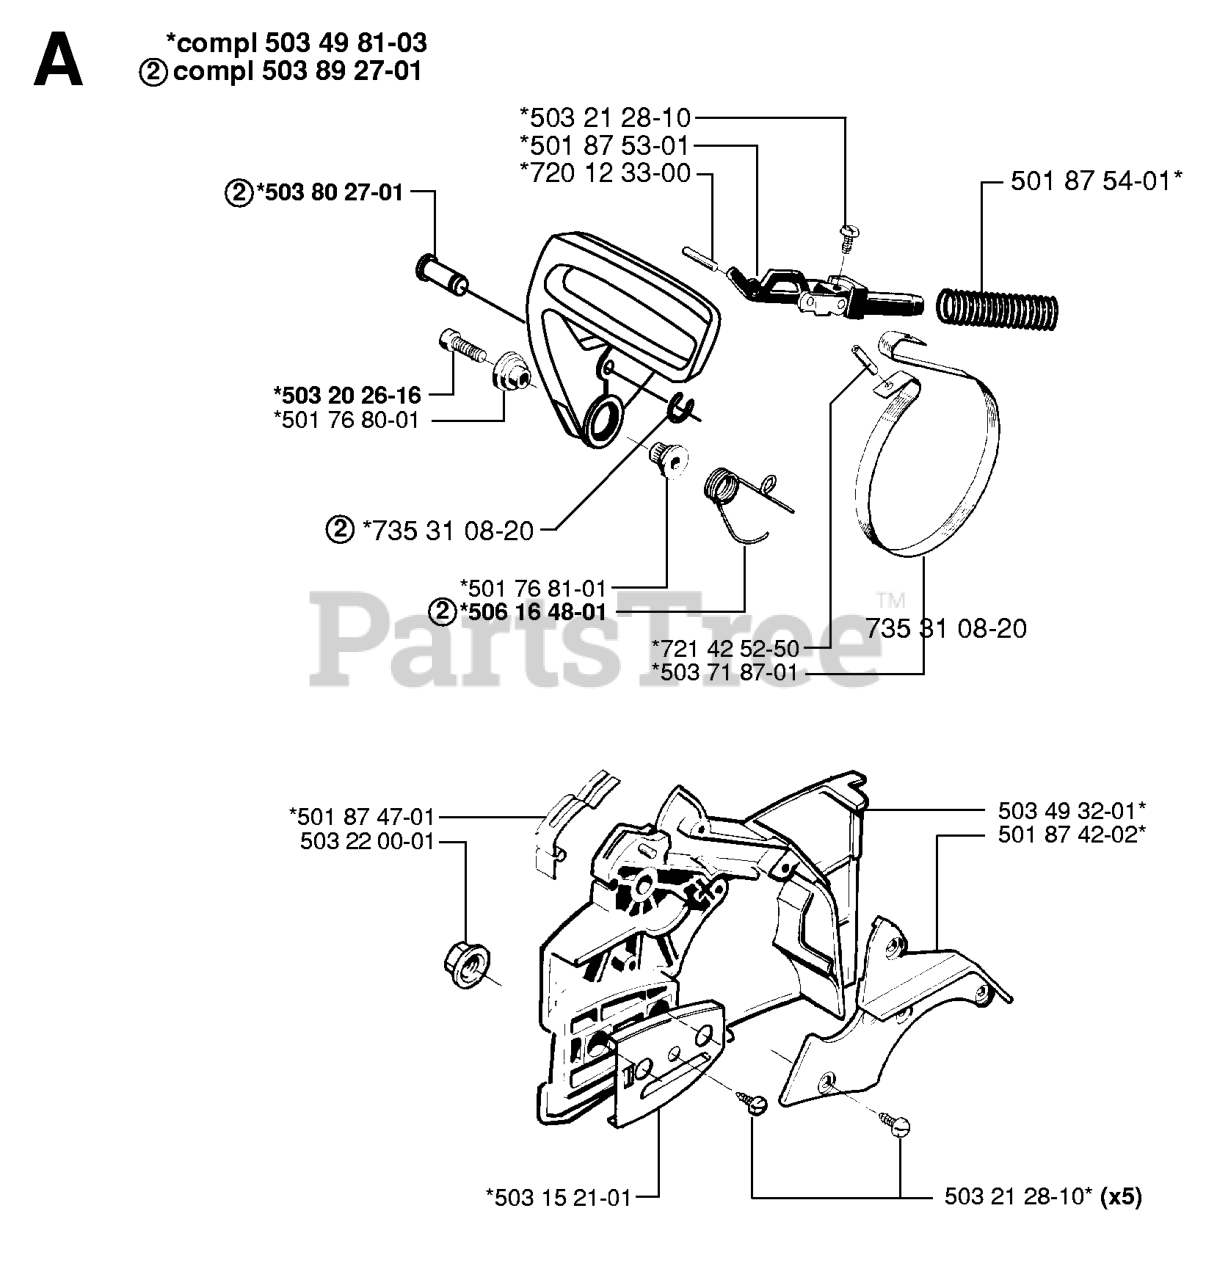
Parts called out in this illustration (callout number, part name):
2	Bushings
3	Seals
9	Gaskets
11	Tubes
16	Crankshafts
24	Woodruff Key
26	Rings
28	Pins
29	Rods
32	Screws
250	Retainers
252	Collections
306	Shields
307	Screws
447	Screws
505	Nuts
562	Screws
